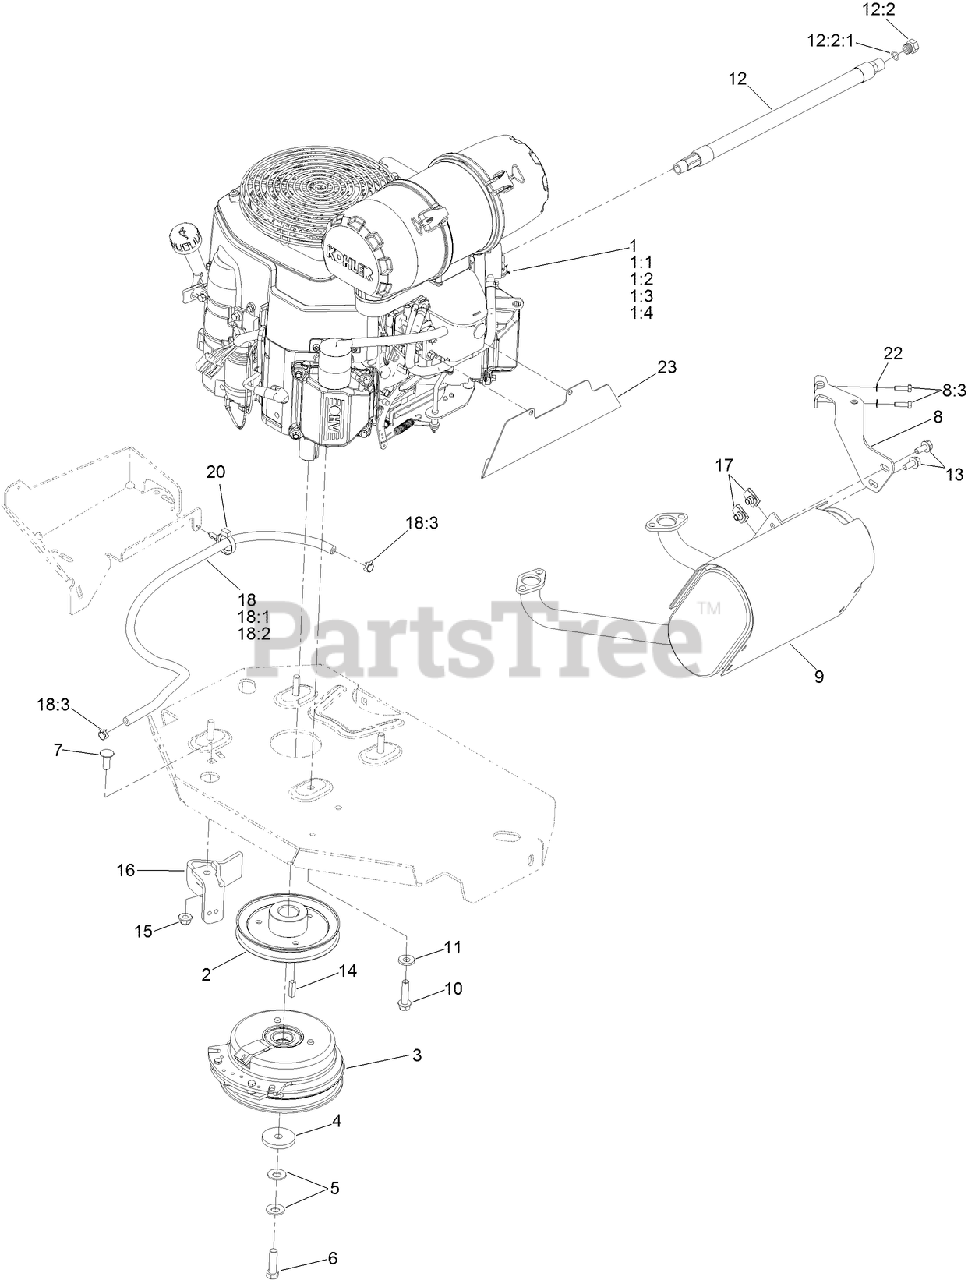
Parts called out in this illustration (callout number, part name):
1:1	KOHLER 52 050 02-S ENGINE OIL FILTER
1:2	KOHLER 25 083 01-S ENGINE AIR FILTER
1:3	KOHLER 25 083 04-S SAFETY FILTER
1:4	KOHLER 24 050 13-S FUEL FILTER
2	SHEAVE-PUMP, DRIVE
3	CLUTCH KIT
4	WASHER-CLUTCH
5	WASHER-SPRING
6	SCREW-HH
7	SCREW-CARR
8	MUFFLER BRACKET KIT
8:3	SCREW-HH
9	MUFFLER KIT
10	SCREW-HWH
11	WASHER-BELLEVILLE
12	OIL DRAIN HOSE ASM
12:2	PLUG-HH
12:2:1	O-RING
13	SCREW-HHF
15	NUT-HF, NI
16	CLUTCH-ANCHOR
17	NUT-U
18	FUEL LINE ASM
18:1	HOSE-FUEL
18:2	SLEEVE-THERMAL
18:3	CLAMP-HOSE
20	CLAMP-HOSE
22	WASHER-SPRING
23	SHIELD-HEAT, CARBURETOR
